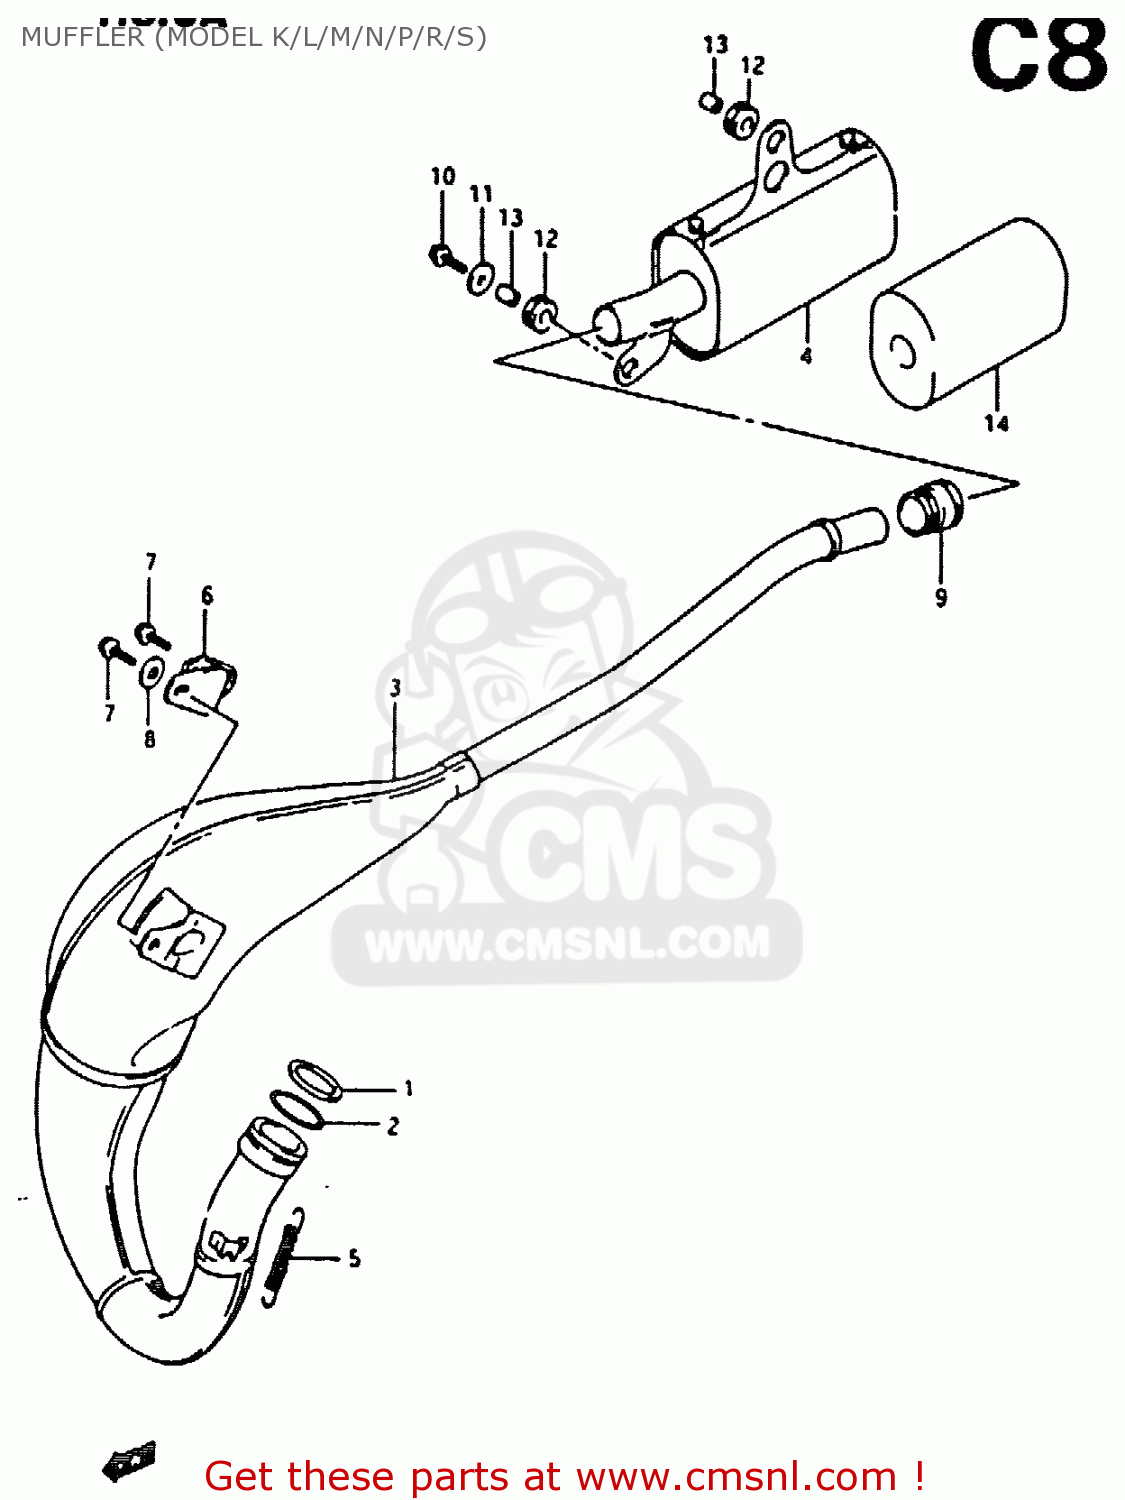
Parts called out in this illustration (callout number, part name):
1	WASHER,EXH FLANGE
2	O RING,EXH FLANGE
3	BODY,MUFFLER
4	BODY,MUFFLER
5	SPRING
6	DAMPER,MUFFLER SUPPORT
7	BOLT
8	WASHER(6.5X16X1.2)
9	CONNECTOR,MUFFLER
10	BOLT
11	WASHER (6.5X20X1.2)
12	CUSHION
13	SPACER
14	SILENCER,MUFFL
16	BOLT 6X25
17	NUT 6MM
18	COVER,MUFFLER
19	SCREW
20	WASHER,LOCK
21	WASHER
22	SPACER
23	CUSHION
